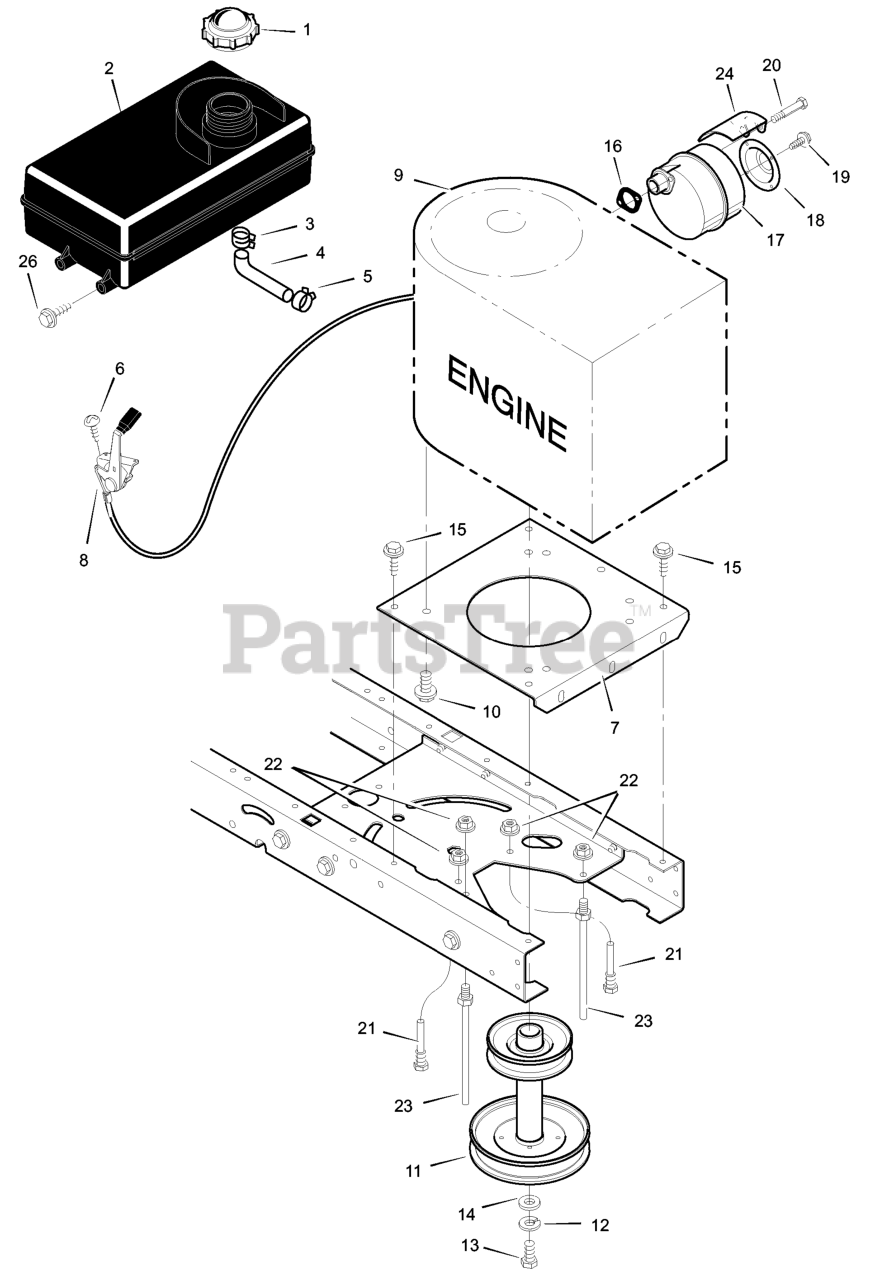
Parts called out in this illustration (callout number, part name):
1	Fuel Cap
2	TANK, Fuel 1.4 Gal.
3	Hose Clamp
4	Fuel Line (Must cut to length)
5	Hose Clamp
7	Plate, Engine
8	Throttle Control
9	Engine *
10	Bolt, Engine Mount
11	STACK PULLEY ASSEMBLY
12	Lockwasher
13	Bolt, Hex
16	GASKET, Exhaust
17	Muffler
18	Deflector, Muffler
20	Bolt, Hex
21	Guide, Belt
22	Nut, Flange
23	Guide, Belt
24	Shield, Heat
